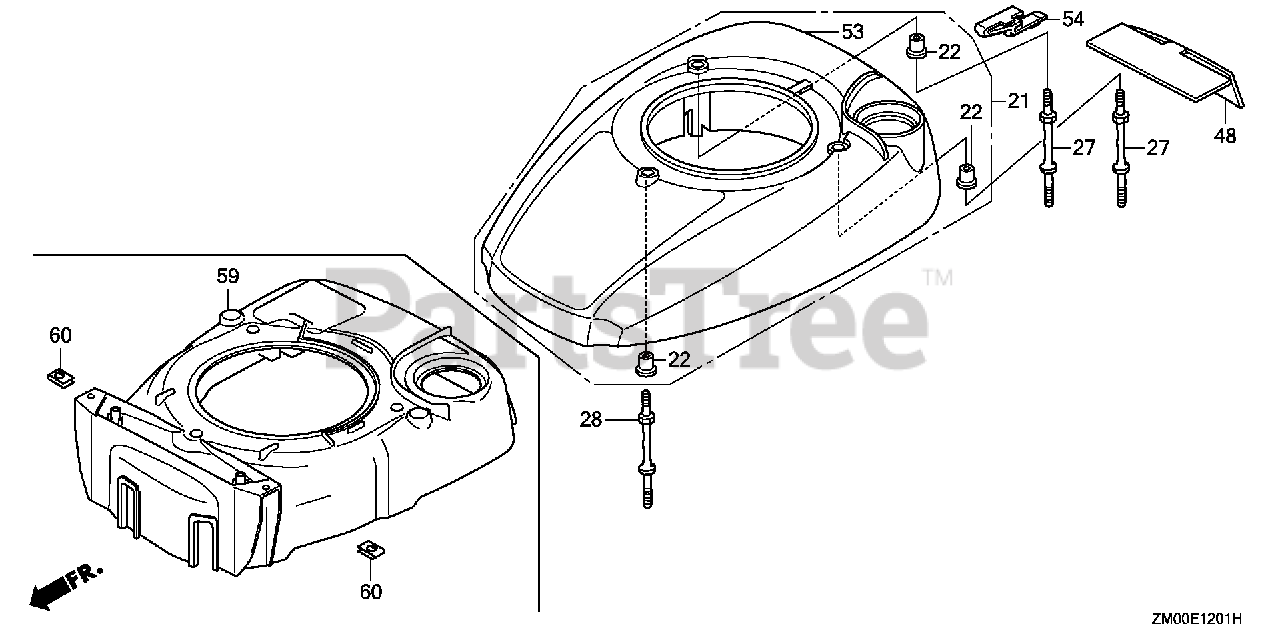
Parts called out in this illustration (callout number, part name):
27	BOLT, STUD (FAN COVER)
28	BOLT, STUD (FAN COVER)
53	COVER, FAN *NH1* (BLACK)
54	CLIP, TANK MOUNTING *NH1* (BLACK)
